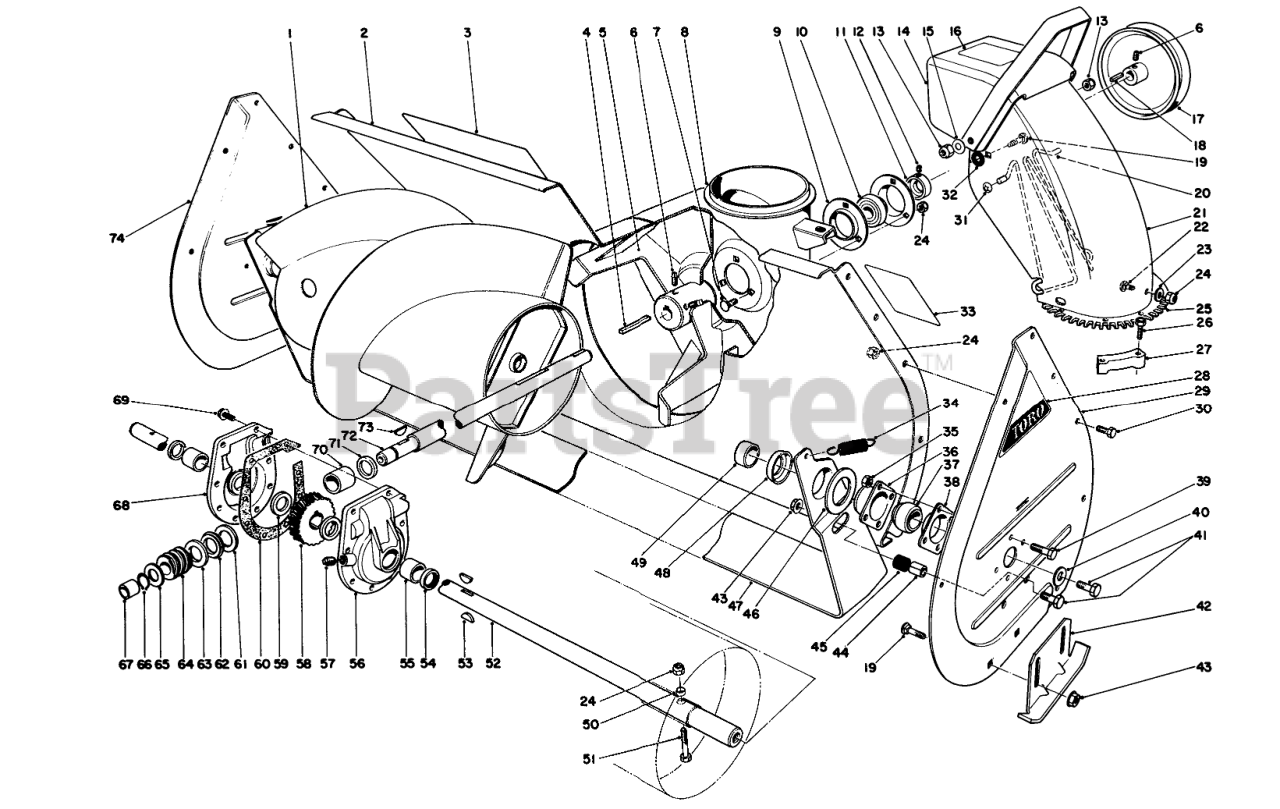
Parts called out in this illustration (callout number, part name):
1	RH AUGER WA 26" B
2	AUGER HSG WA 26" R
3	AUGER WARNING DECAL
5	IMPELLER ASM
6	Set Screw
7	BOLT-CARR
8	CHUTE RING
9	BRG FLANGE
10	BALL BRG W/COLLAR
11	EXT LOCKING COLLAR
12	SCREW-HSH
13	NUT-LOCK, CONE
14	Deflector (Incl. Ref. #16)
15	WASHER-BELLEVILLE
16	Decal-Danger
17	1/2 X 9.5 DIA PULLEY
18	SQUARE KEY
19	SCREW-CARR
20	CHUTE WIRE
21	Chute-Upper
22	SCREW-CARR
23	WASHER-PLAIN
24	NUT-LOCK, NI
25	Screw
26	SCREW-SPECIAL
27	RETAINER-CHUTE
28	AUGER SIDE PLT DECAL
29	LH AUGER SIDE PLT R
30	SCREW-HH
31	NUT-PUSH
32	WASHER-RUBBER
33	DECAL-WARNING, AUGER
34	SPRING-TENSION
35	NUT-LOCK, CONE
36	BEARING-FLANGE, FRONT
37	BEARING
38	BEARING-FLANGE, REAR
39	SCREW-HH
40	WASHER
41	SCREW-HH
42	AUGER SKID WA R
43	NUT-HF
44	SCRAPER STOP SPACER
45	SCRAPER STOP CUSHION
46	SCRAPER BLADE SPACER
47	SCRAPER BLADE 26 R
48	Positioner-Scraper
49	AUGER SPACER
50	SPACER-HUB, AUGER
51	Auger Bolt
52	26 AUGER SHAFT
53	KEY-WOODRUFF
54	SEAL-OIL
55	BUSHING
56	Bear Case L.H. (Incl. Ref. #54-55)
57	PLUG-PIPE, SQH
58	GEAR-WORM, 27T
59	WASHER-THRUST
60	GASKET-CASE, GEAR
61	WASHER-THRUST
62	BEARING-THRUST
63	THRUST-WASHER
65	WASHER-THRUST
66	Ring-Snap
67	BUSHING
68	Gear Case R.H. (Incl. Ref. #54-55)
69	SCREW-TAPTITE
70	BUSHING-SPECIAL
71	RING-QUAD
72	SHAFT-IMPELLER
73	KEY-WOODRUFF
74	RH AUGER SIDE PLT R
